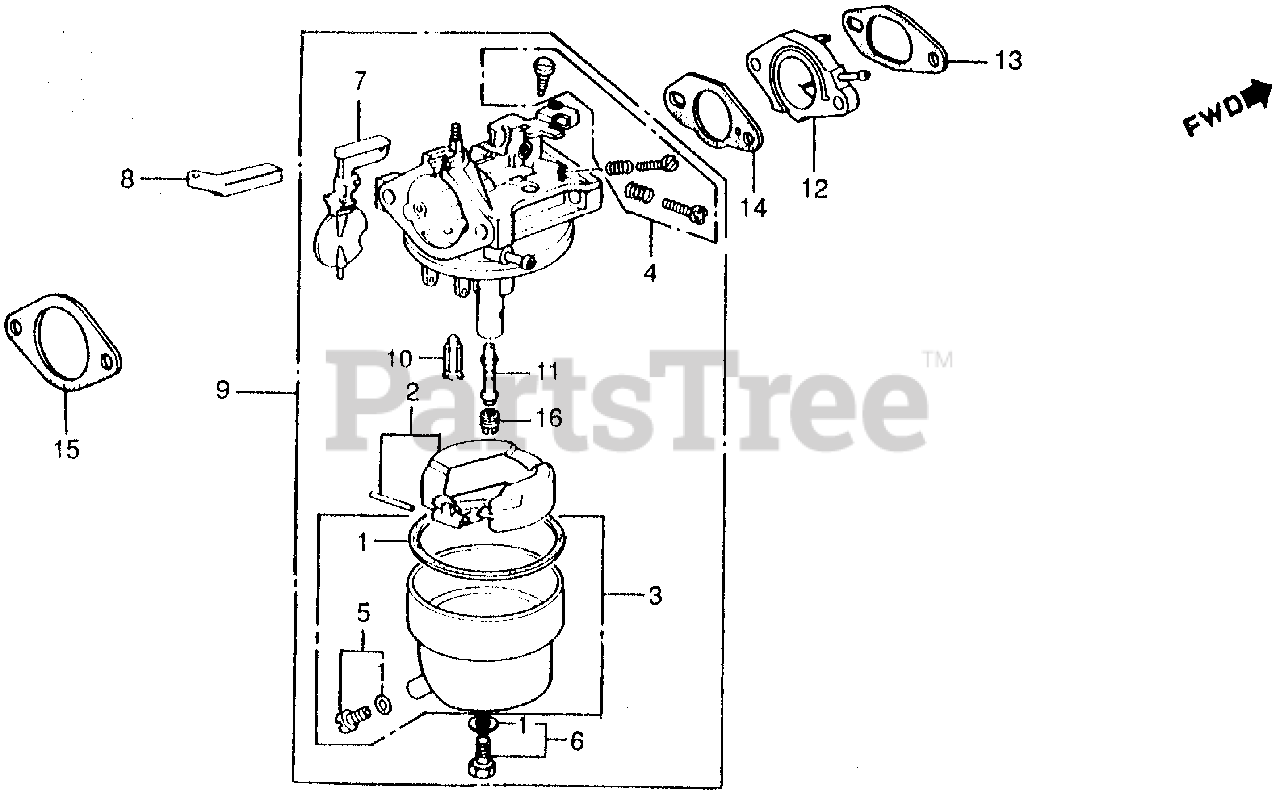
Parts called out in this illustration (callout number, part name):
1	GASKET SET
3	CHAMBER SET, FLOAT
4	SCREW SET A
5	SCREW SET, DRAIN
6	SCREW SET B
8	ARM, CHOKE LEVER
9	CARBURETOR ASSY. (BB30D C)
10	VALVE, FLOAT
11	NOZZLE, MAIN
12	INSULATOR, CARBURETOR
13	GASKET, INSULATOR
14	GASKET, CARBURETOR
15	GASKET, AIR CLEANER
16	JET, MAIN (#68)
16	JET, MAIN (#70)
16	JET, MAIN (#72)
